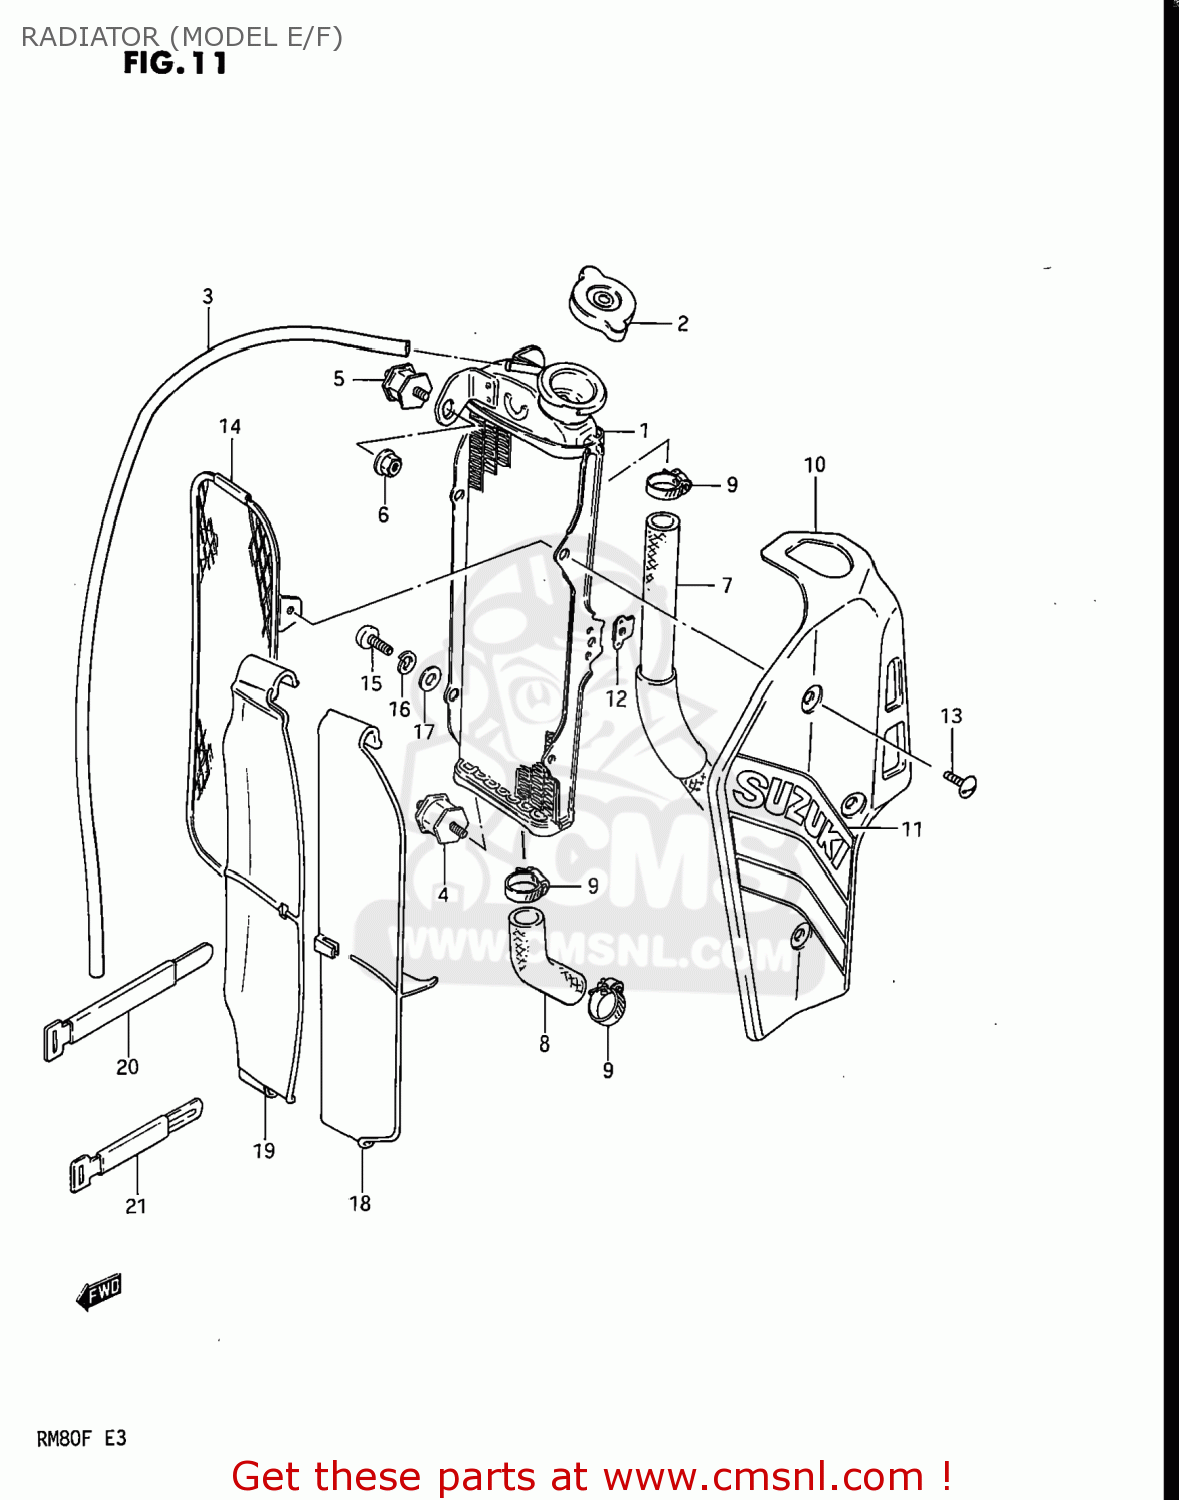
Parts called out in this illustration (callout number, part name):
1	RADIATOR ASSEMBLY,WATER
2	CAP,RADIATOR 1.1
3	HOSE
4	CUSHION,RADIATOR
5	CUSHION
6	NUT 6MM
7	HOSE,RADIATOR INLET
8	HOSE,RADIATOR OUTLET
9	CLAMP
10	COVER,RADIATOR
11	TAPE SET,RADIATOR COVER
12	PLATE,RADIATOR COVER FITING
13	SCREW(6X14)
14	BUMPER,RADIATOR
15	SCREW
16	WASHER,LOCK
17	WASHER
18	LOUVER,RADIATOR
19	LOUVER,RADIATOR
20	CLAMP
21	CLAMP
